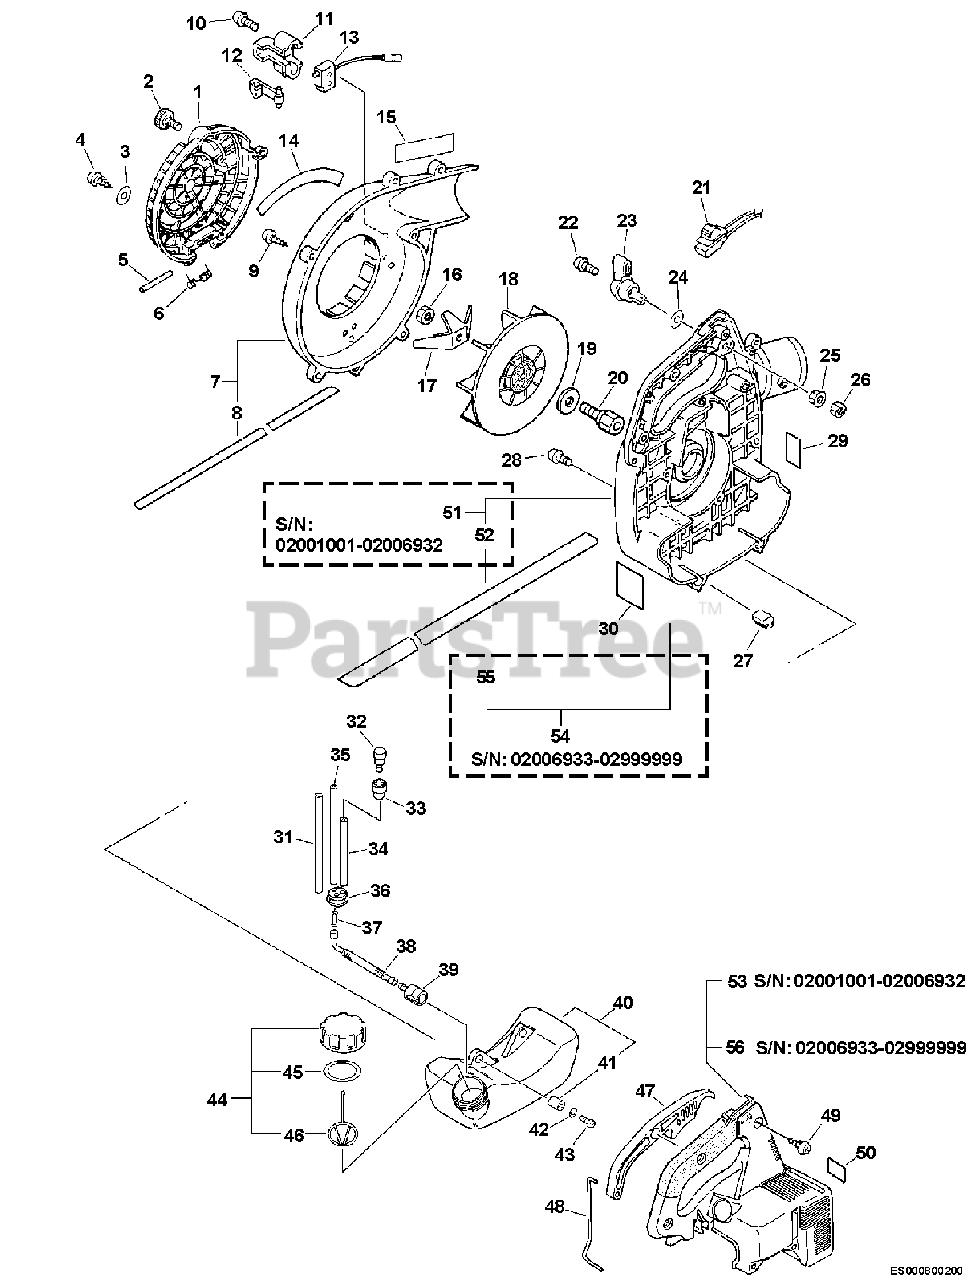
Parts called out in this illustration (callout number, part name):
1	COVER, INTAKE
2	THUMBSCREW
3	WASHER 5.5×12×0.8
4	SCREW 5×14
5	PIN, INTAKE COVER
6	SPRING, COIL
7	FAN CASE ASSY - LEFT
9	SCREW, TAPPING 5×20
10	SCREW 4×22
11	BRACKET, SWITCH
12	LEVER, ACTUATOR
13	SWITCH, INTERLOCK
14	LABEL, MODEL
15	LABEL, CAUTION
17	SHREDDER
20	HUB, FAN
21	IGNITION SWITCH ASSY
22	SCREW 5×25
23	CONTROL, THROTTLE
24	WASHER 5.5×12×0.8
25	NUT, FLANGE M5
28	SCREW 4×22
29	LABEL - CAUTION -- SPANISH
30	LABEL - CAUTION
31	PIPE, FUEL RETURN 3×6×90 MM CLEAR
32	VENT ASSY
33	HOLDER, VENT
34	PIPE, FUEL 3x-5x-70 BLACK
35	PIPE, FUEL 3×5×90 BLACK
36	GROMMET, FUEL
37	CONNECTOR, PIPE
38	PIPE, FUEL 3×7×100 FLEXIBLE
39	FILTER, FUEL
40	TANK ASSY, FUEL
41	SPACER 6.2×7.8×6
42	WASHER 5.5×12×0.8
43	SCREW 5×16
44	CAP ASSY, FUEL
45	GASKET, FUEL CAP
46	CONNECTOR, CAP L= 100 MM
47	CONTROL, THROTTLE
48	ROD, THROTTLE
49	SCREW, TAPPING 5×20
50	LABEL, CAUTION - HOT
51	FAN COVER ASSY - RIGHT
52	CUSHION
53	COVER, ENGINE - GRAY
54	FAN COVER ASSY - RIGHT -- GRAY
55	CUSHION
56	COVER, ENGINE - GRAY
